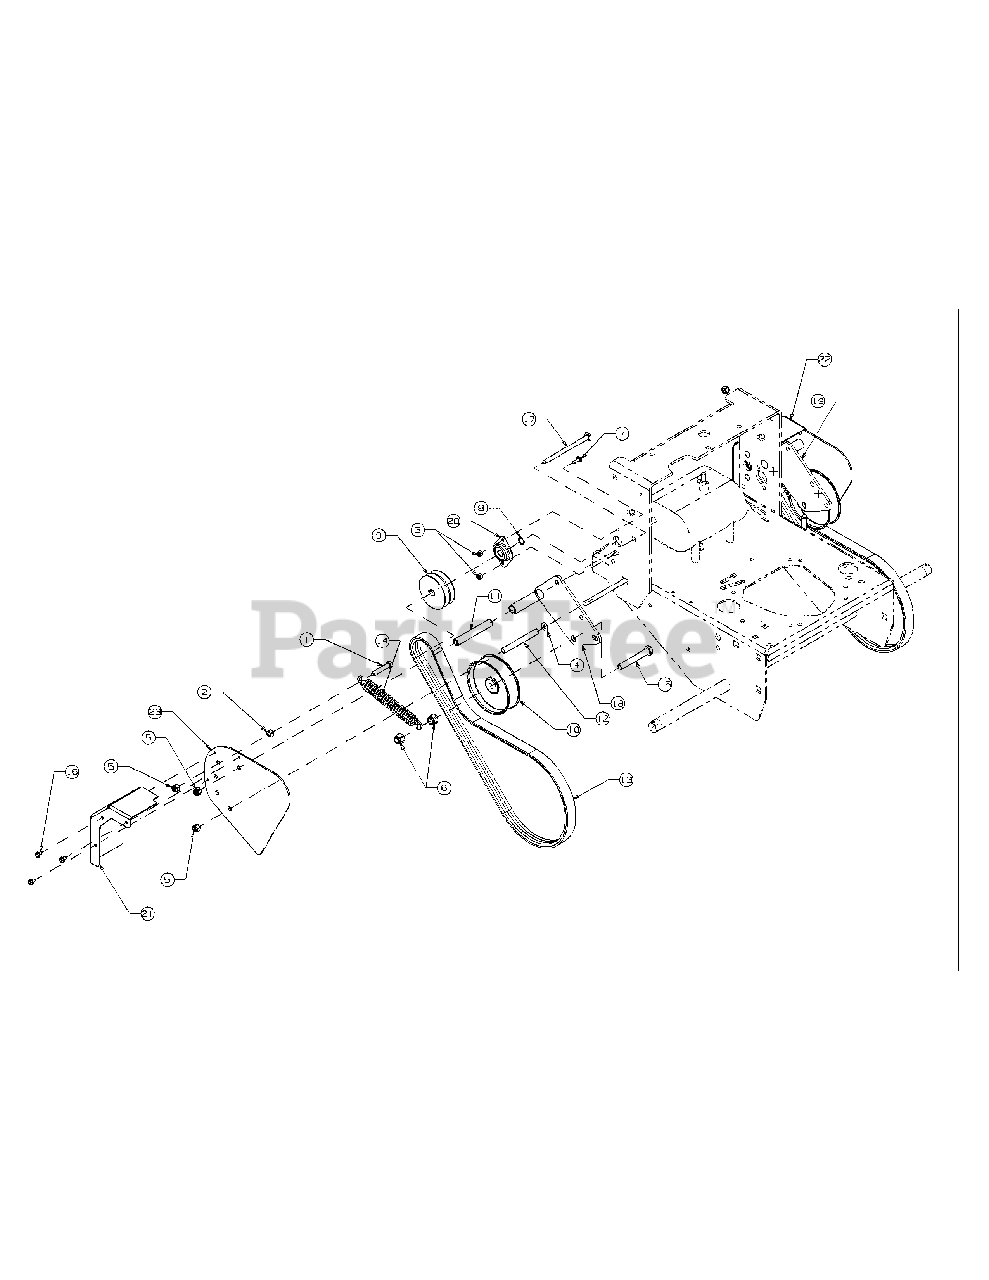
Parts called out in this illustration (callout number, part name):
1	Hex Cap Screw, 3/8-16, 2.00
2	Hex Nut, 3/8-16
3	Lock Nut, Nylon Insert, 1/4-20
4	Flat Washer
5	Lock Nut, Nylon Insert, 3/8-16
6	Lock Nut, Nylon Insert, 1/2-13
7	Carriage Bolt, 1/4-20 x .750
8	External Retain Ring
9	Jackshaft Pulley
10	Flat Idler Drive
11	Idler Sleeve
12	Spacer Tube
14	Extension Spring
15	Hex Cap Screw, 1/2-13, 3.50
16	Screw, TT, 1/4-20, 0.5, Hex Index Washer
17	Carriage Bolt, 3/8-16 x 5.50
18	Right Idler Bracket
19	Left Idler Bracket
20	Bearing Housing
21	Right Hand Outer Belt Cover
22	Left Hand Outer Belt Cover
